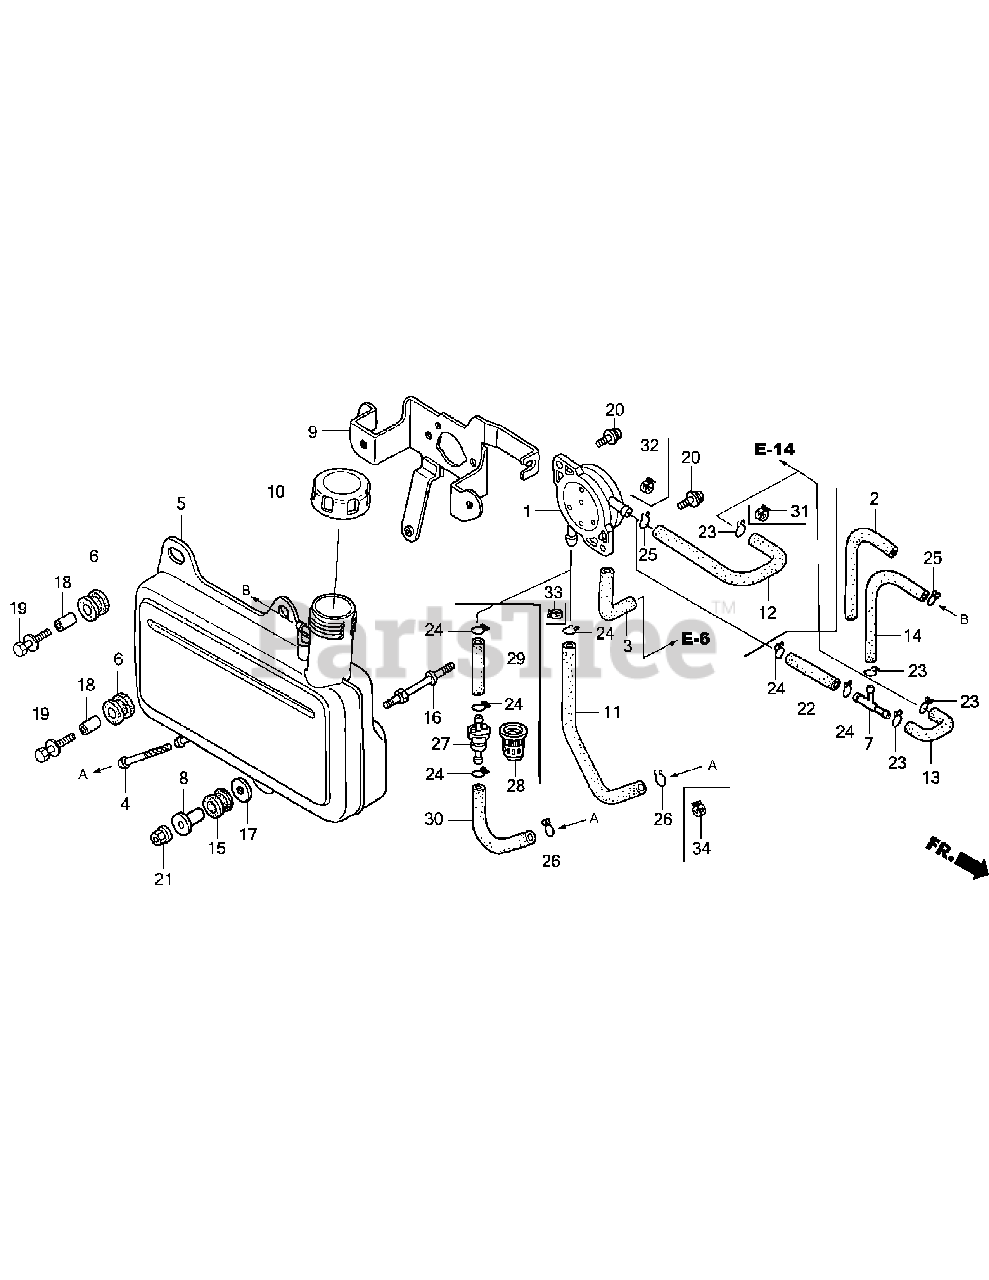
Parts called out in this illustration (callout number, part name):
1	PUMP ASSY., FUEL
2	RUBBER, SUPPORTER (107MM)
3	TUBE, DIAPHRAGM
5	TANK, FUEL
6	RUBBER B, TANK MOUNTING
7	JOINT, FUEL TUBE
8	COLLAR, FUEL TANK SETTING
9	STAY A, FUEL TANK
10	CAP ASSY., FUEL TANK
13	TUBE, FUEL
14	TUBE, FUEL RETURN
15	RUBBER, RR. FENDER
16	BOLT, STUD (F/TANK)
17	WASHER (8MM)
18	COLLAR (14X6.1)
19	BOLT-WASHER (6X25)
20	SCREW-WASHER (5X14)
21	NUT, FLANGE (6MM)
22	BULK HOSE, FUEL (5.5X3000) (5.5X33)
23	CLIP, TUBE (B8)
24	CLIP, TUBE (B10)
25	CLIP, TUBE (C9)
26	CLIP, TUBE (C11)
27	FILTER, FUEL
28	SUSPENSION, STRAINER
29	TUBE, FUEL PUMP
30	TUBE, FUEL TANK
